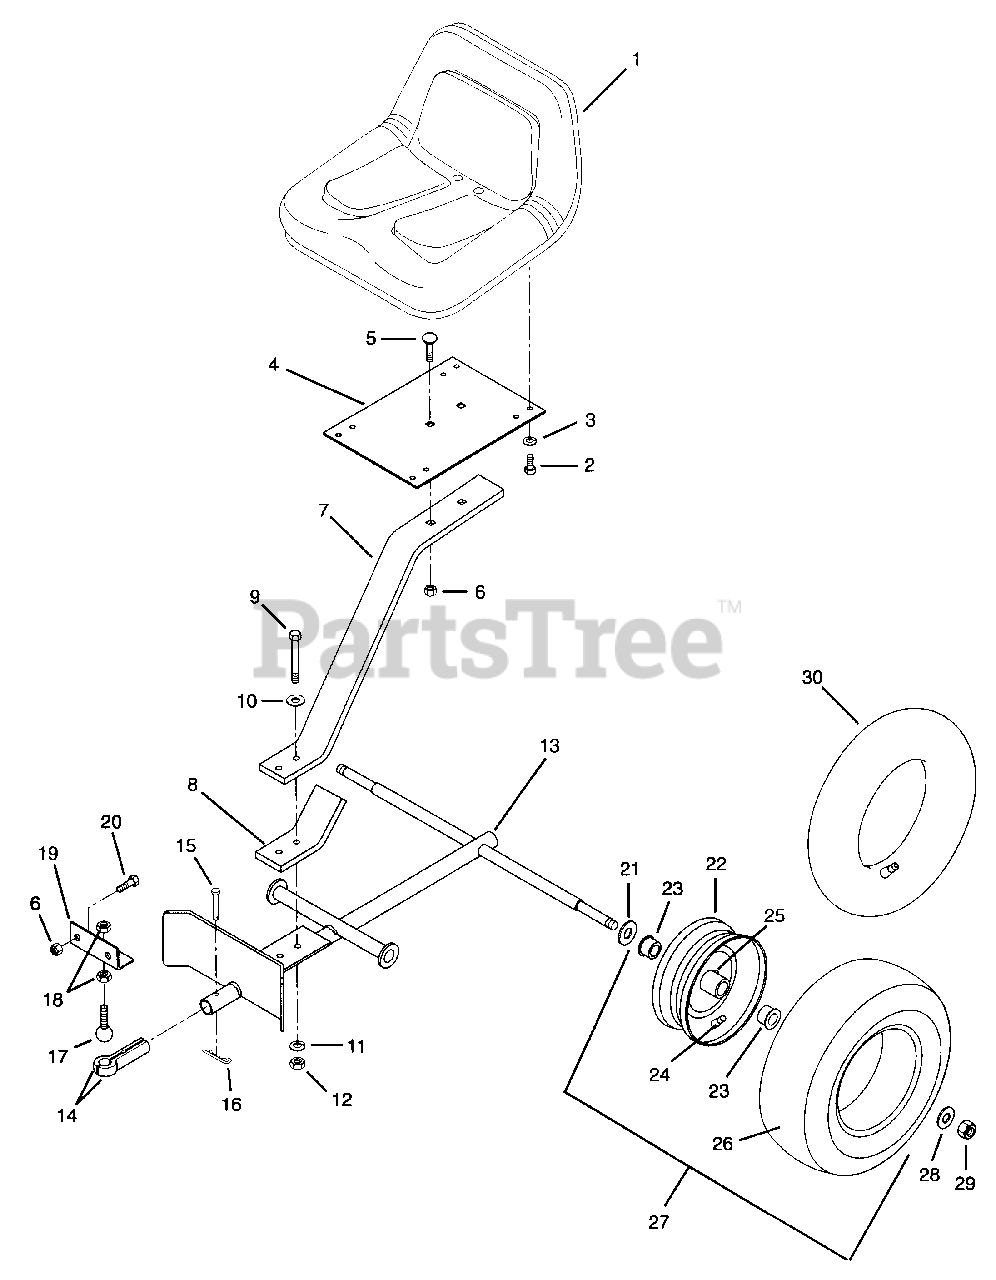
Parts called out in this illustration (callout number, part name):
1	Seat
2	Bolt-Hex .31-18 x .75 Grade 5
3	Washer-Lock .31 x .078
4	Plate
5	Bolt-Round Head Square Neck .50-13 x 1.50
6	Nut-Locking-Center .50-13 Grade 5
7	Seat Support
8	Plate, Reinforcement
9	Bolt-Hex .50-13 x 3.50 Grade 5
10	Washer-Flat-Steel .563 x 1.38 x .109
11	Washer-Lock .50 x .125
12	Nut-Jam .50-13
13	Weldment, Frame
14	Socket, Split
15	Pin, Draw Bar
16	Pin-Hair-Internal .08 x .18 x 1.18
17	Stud, Ball
18	Nut-Jam .625-18
19	Bracket
20	Bolt-Hex .50-13 x 1.25 Grade 5
21	Washer-Flat-Steel .812 x 1.50 x .139
22	Wheel Assembly, less Tire/Tube
23	Bushing, Wheel
24	Fitting, Lube .25-28 x .256
25	Assembly, Valve Stem
26	Tire
27	Wheel 3.5 x 4.6
28	Washer-Flat-Steel .656 x 1.31 x .095
29	Nut-Locking-Nylon .625-18
30	Tube, Tractor Tire
